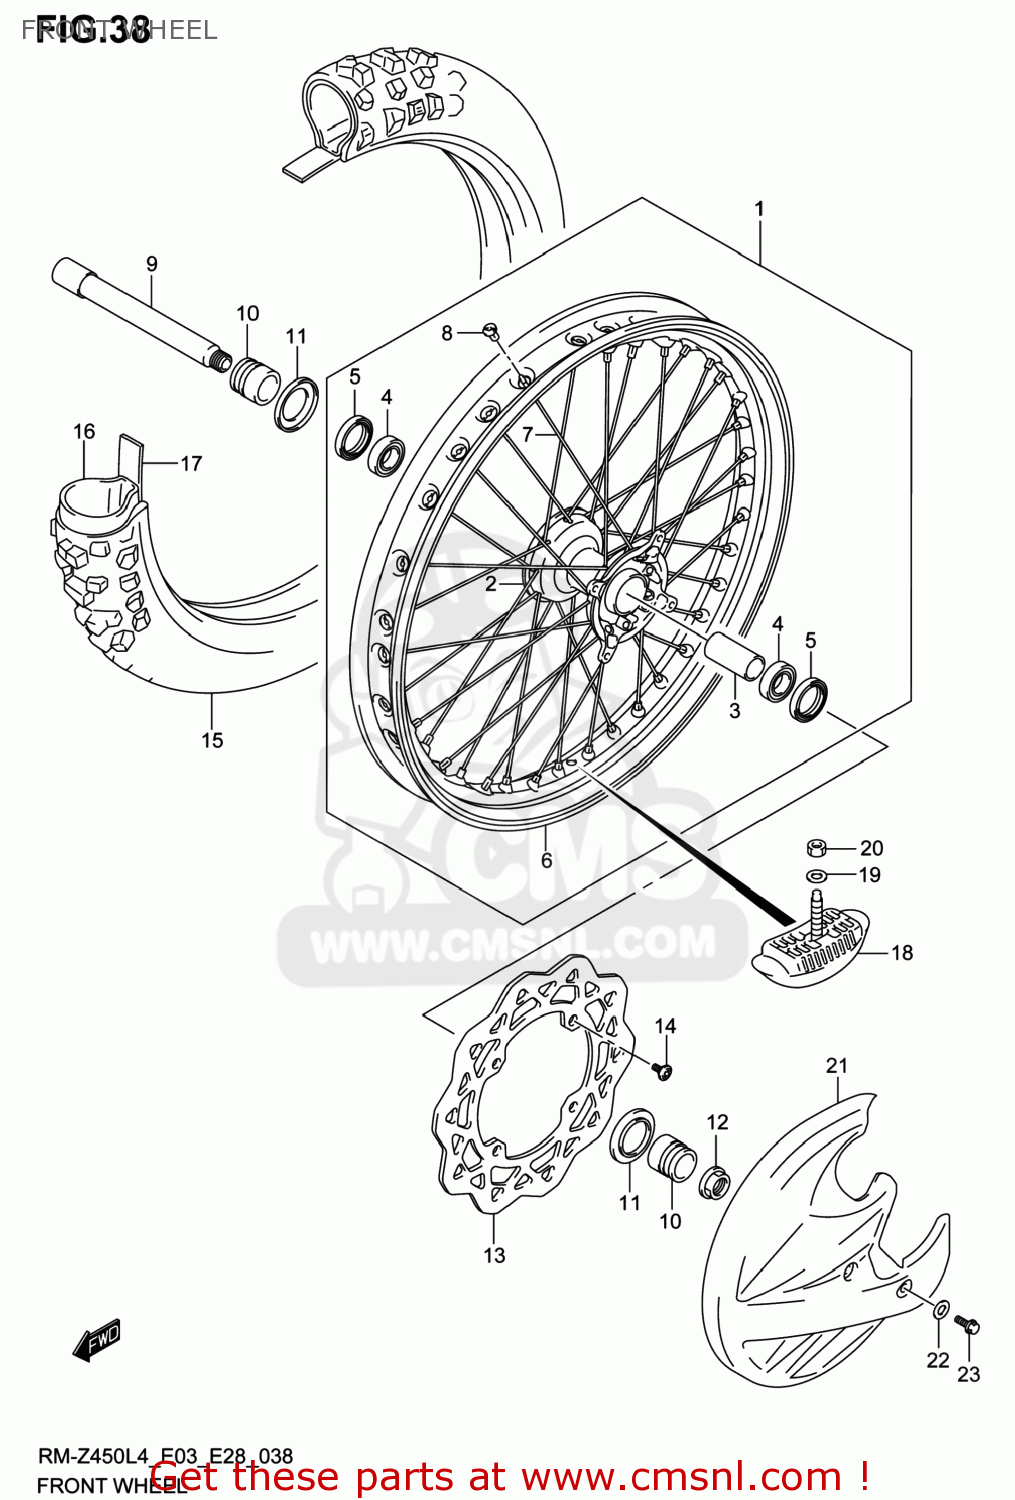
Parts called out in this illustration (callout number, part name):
1	WHEEL ASSY,FR
2	HUB,FR
3	SPACER,FR HUB BEARING
4	BEARING(22X39X9)
5	SEAL,OIL(30X40X7)
6	RIM,FR WHEEL
7	SPOKE,FR WHEEL
8	NIPPLE,FR WHEEL
9	AXLE,FR
10	SPACER,FR AXLE
11	COVER,FR AXLE SPACER
12	NUT
13	DISC,FR BRAKE
14	SCREW(6X13.5)
15	TIRE,FR(80/100 21)
16	TUBE ASSY,WHEEL INNER
17	PROTECTOR,WHL INR TUBE
18	STOPPER,BEAD
19	WASHER
20	NUT
21	COVER,FR BRAKE DISC
22	WASHER,FR BRAKE DISC COVER
23	BOLT(6X12)
